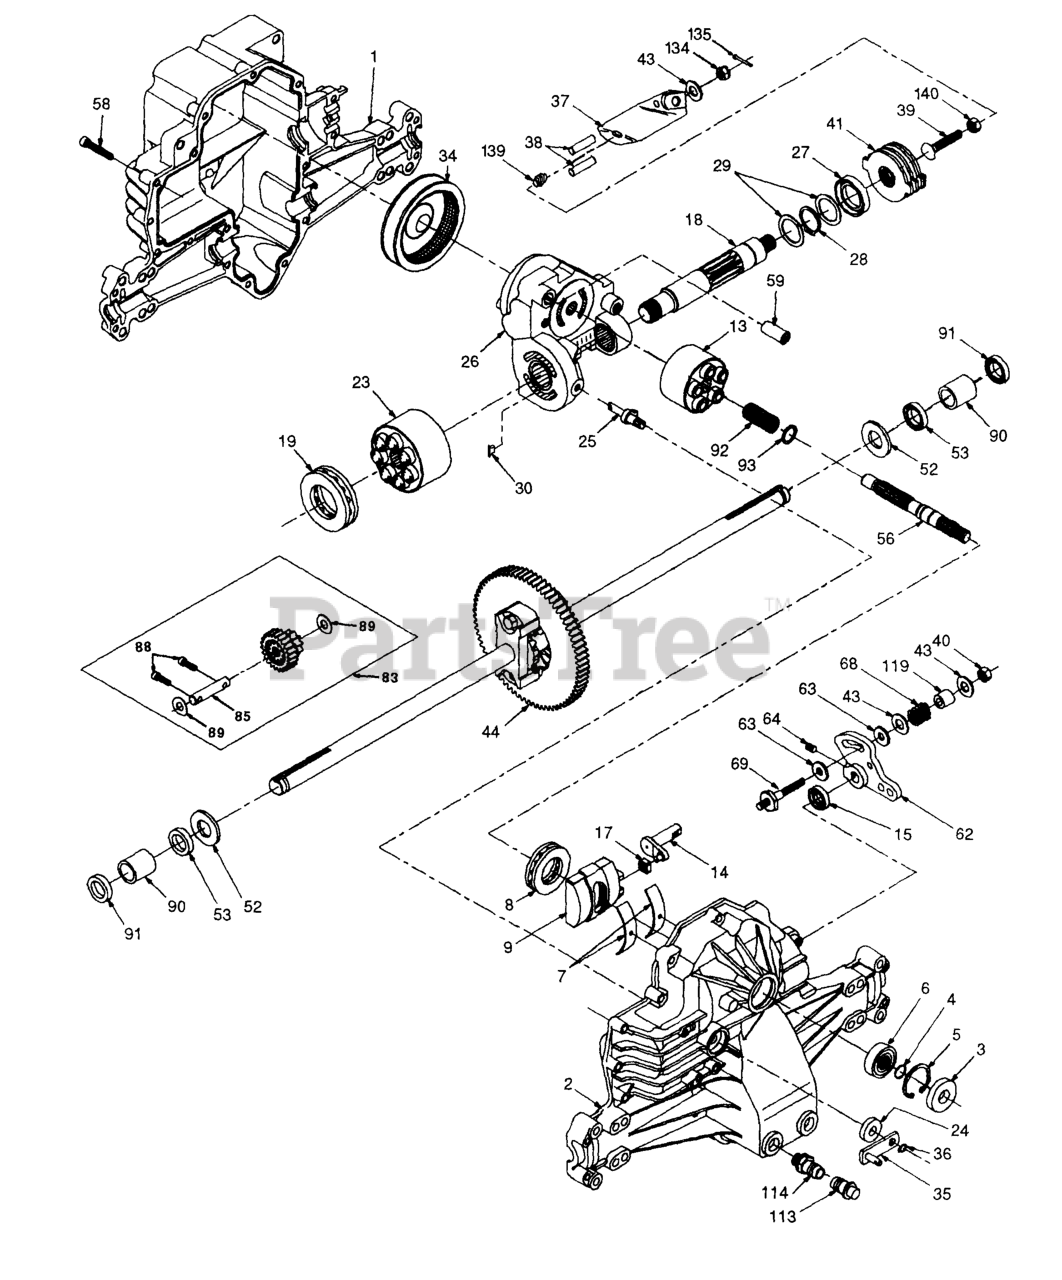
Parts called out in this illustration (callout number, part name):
1	LOWER HOUSING
2	HOUSING UPPER 70255
3	SEAL.LIP.H-G.(9008000-0128)
4	RING RETAINING 2003016
5	RING.RETAINING.(2003052)
6	BALL BEARING
7	CRADLE BEARING
8	BEARING, THRUST 50551
9	SWASHPLATE (2003087)
13	BLOCK, CYL ASSY
14	TRUNNION ARM
17	SLOT GUIDE
18	SHAFT, MOTOR
19	BEARING, THRUST 50552
23	BLOCK, CYL ASSY
25	BYPASS ACTUATOR
26	CENTER SECTION ASS'Y KIT
28	RETAINING RING
34	ELEMENT, OIL FILTER
35	BYPASS ARM
36	RETAINING RING 44870
37	ACTUATING ARM
38	ACTUATING PIN 44891
39	BOLT 5/16-24 X 1-3/4
40	LOCKNUT, HEX 5/16-24
41	BRAKE ROTOR 70135 HYDRO-GEAR
43	WASHER .34X.88X.06.44130
44	KIT SVC DIFFRENTIAL 70130
52	WASHER.HYDRO-GEAR 44875
53	SEAL.HYDRO.53901
56	SHAFT.INPUT.50005
58	BOLT #44876
62	CONTROL ARM 50254
63	DAMPENER PUCK
64	SCREW.SET.50018
68	SPRING HELICAL COMP 50277
69	STUD 5/16-24 50284
83	JACK SHAFT ASSY
89	WASHER 50132
90	SLEEVE.BEARING 50118
91	RP SEAL, WIPER
92	SPRING 2003014
113	CAP, VENT ASSY
114	O-RING KIT 70110
119	SPACER.HYDRO GEAR 50278
134	NUT.CAS.HYD.44142
135	ID DOT HYDD
139	SPRING, COMPRESSION 50431
140	NUT, HEX 5/16-24
